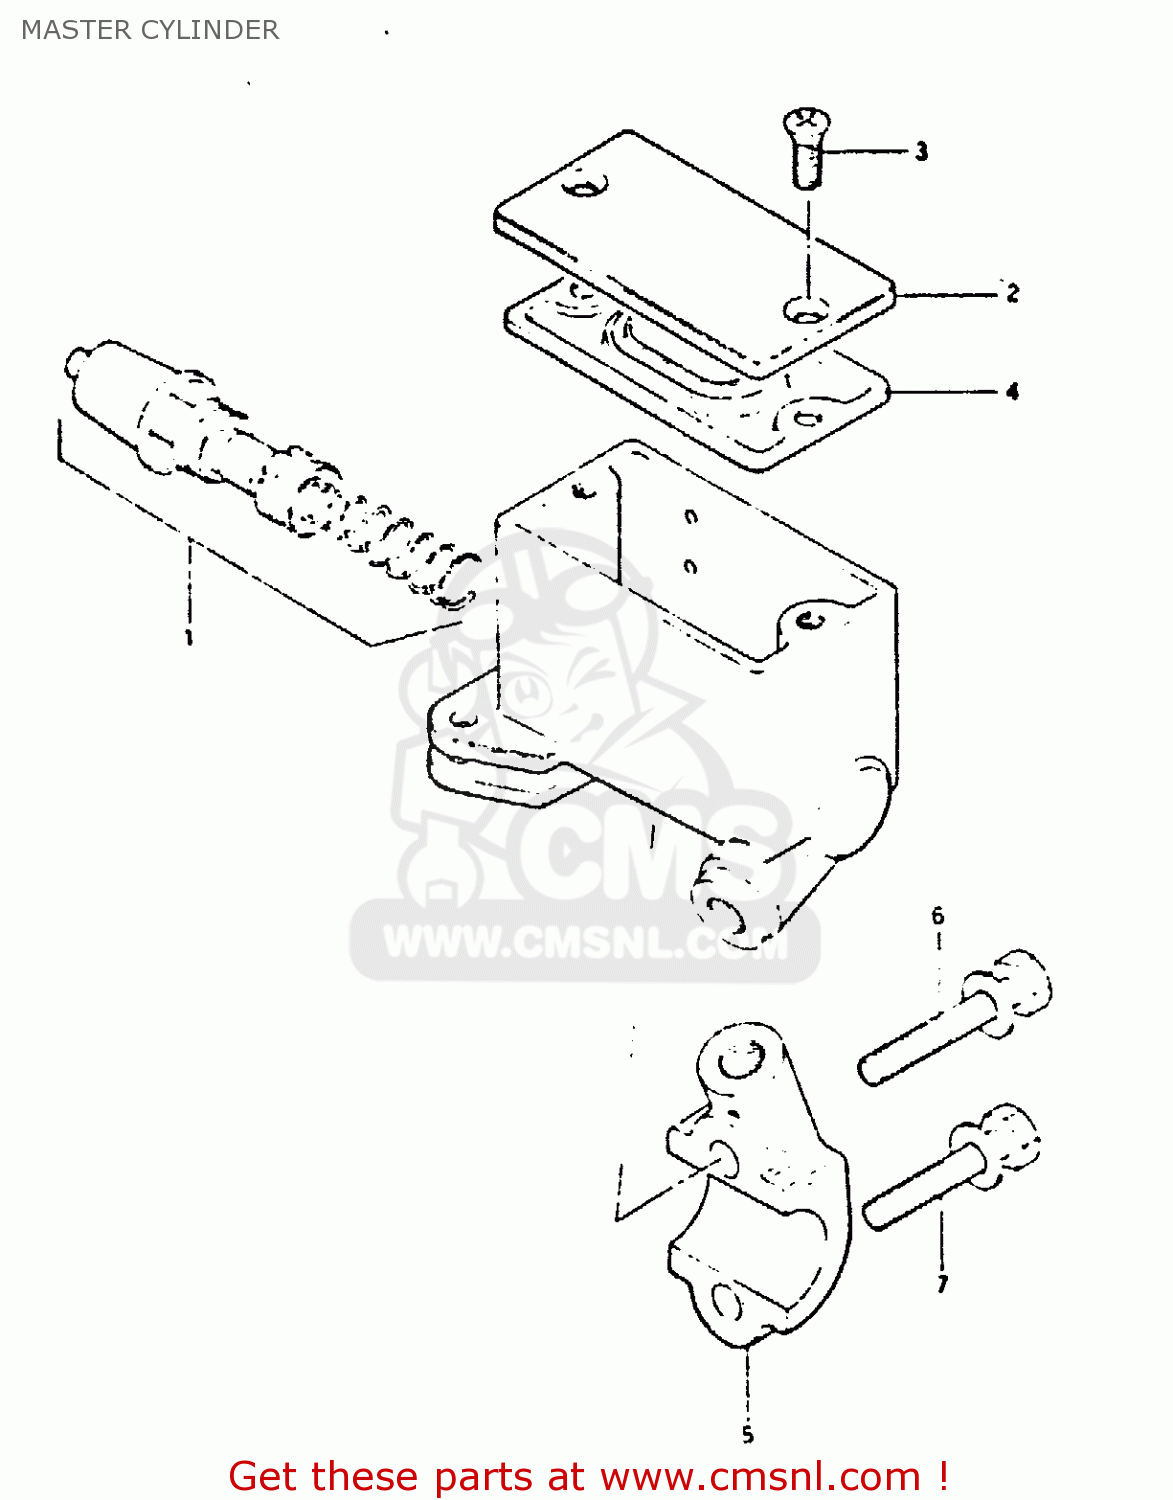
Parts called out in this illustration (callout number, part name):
1	PISTON & CUP SET
2	CAP
3	SCREW,RESERVOIR CAP
4	DIAPHRAGM,MASTER CYLINDER
5	HOLDER
6	BOLT,MASTER CYLINDER H
7	BOLT,MASTER CYLINDER H
